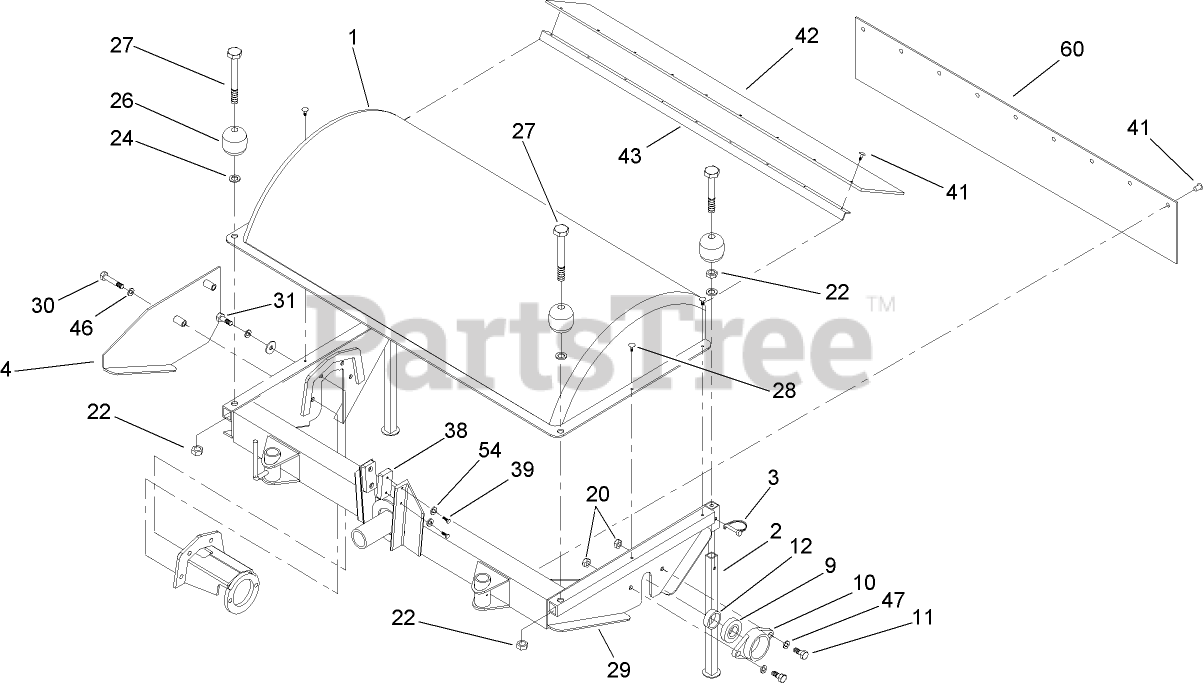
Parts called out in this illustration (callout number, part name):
1	COVER-BROOM
2	STAND-HEAD, BROOM
3	PIN-LYNCH
4	PLATE-GUARD, MOTOR
9	BEARING
10	HOUSING-BEARING
11	SCREW-HH
12	COLLAR-LOCKING
20	NUT-HEX
22	NUT-JAM
24	WASHER
26	ROLLER
27	SCREW-HH
28	SCREW
29	BROOM HEAD FRAME ASM
30	SCREW-HH
31	SCREW-HH
38	BUMPER-RUBBER
39	SCREW-HH
41	RIVET-POP
42	BELTING-RUBBER
43	PLATE-MOUNT, GUARD
46	WASHER-LOCK
47	WASHER-FLAT
60	FLAP-REAR
